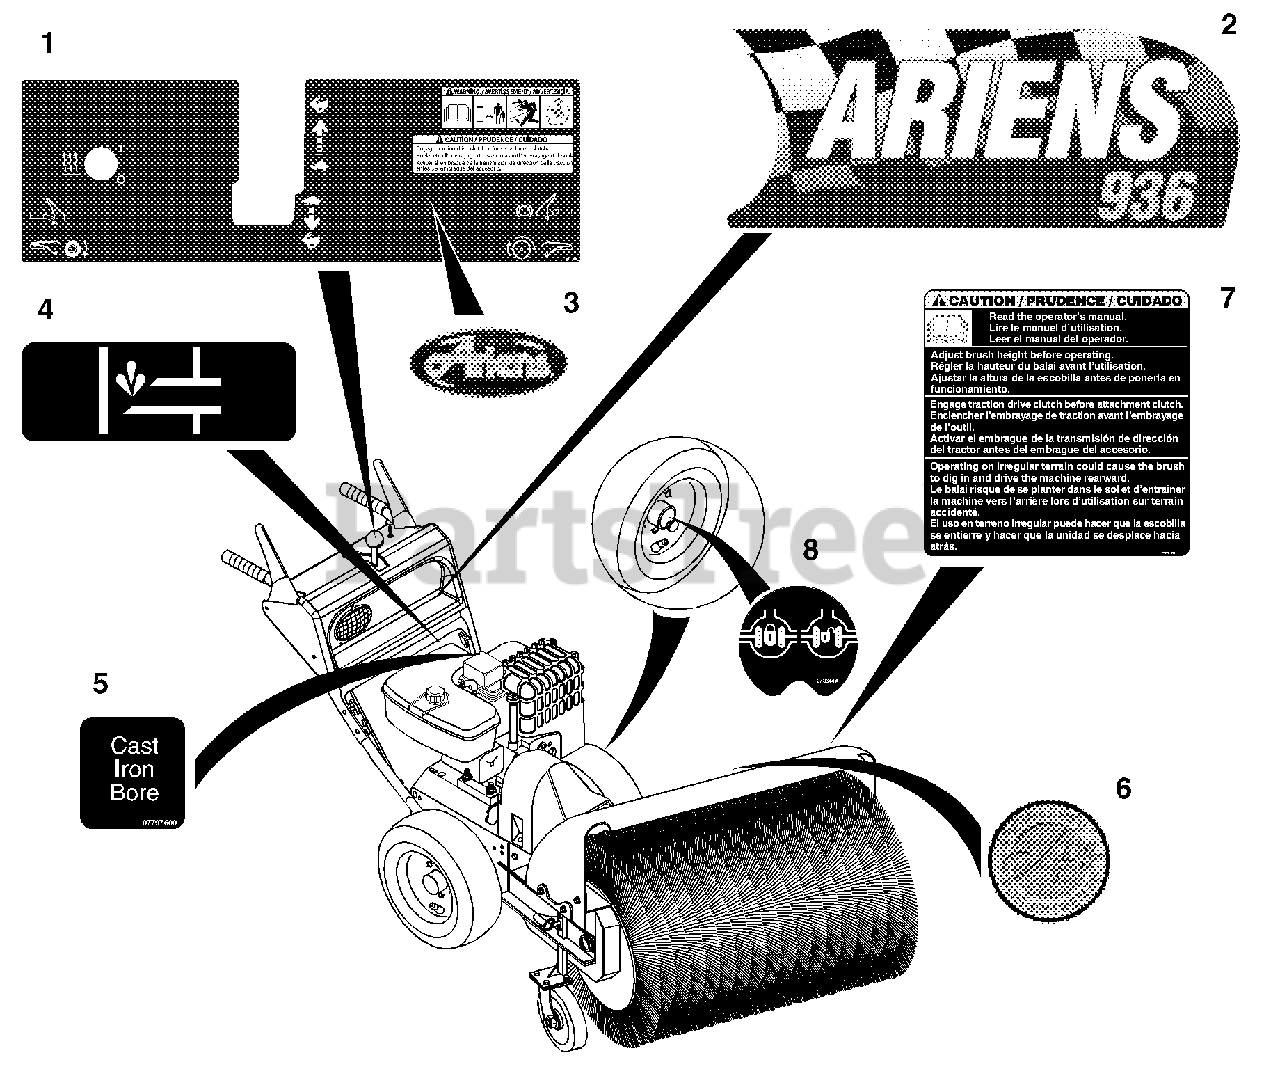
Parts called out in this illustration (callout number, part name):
1	DECAL, CONTROL - 936
2	DECAL, FRONT PANEL - 936
3	DECAL, "ARIENS" JEWEL
4	DECAL, PRIMER "TECUMSEH'S"
5	DECAL - CAST IRON BORE
6	DECAL, A+
7	DECAL, DANGER - POWER BRUSH
8	DIFFERENTIAL LOCK DECAL
